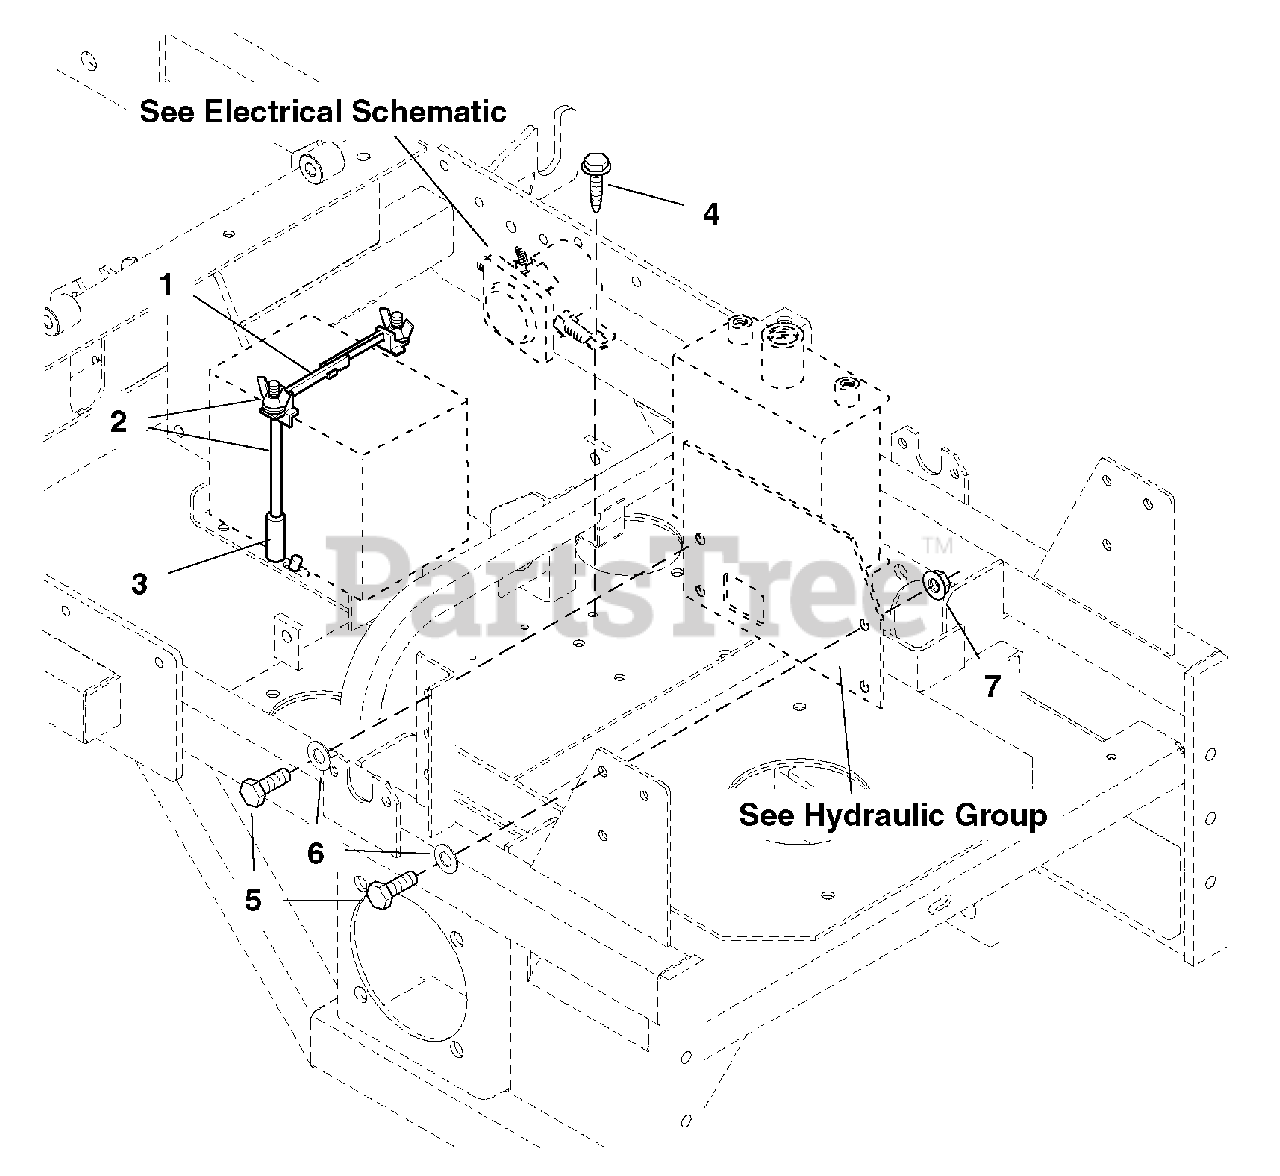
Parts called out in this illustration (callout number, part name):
1	BATTERY HOLDDOWN
2	BATTERY HOLDDOWN BOLT
4	CAPSCREW, Hex Hd, Self-Tap, 1/4-20-3/4
5	CAPSCREW, Hex Hd, 5/16-18 x 1
6	WASHER, 5/16
7	NUT, Hex, Serrated Flange, 5/16-18
